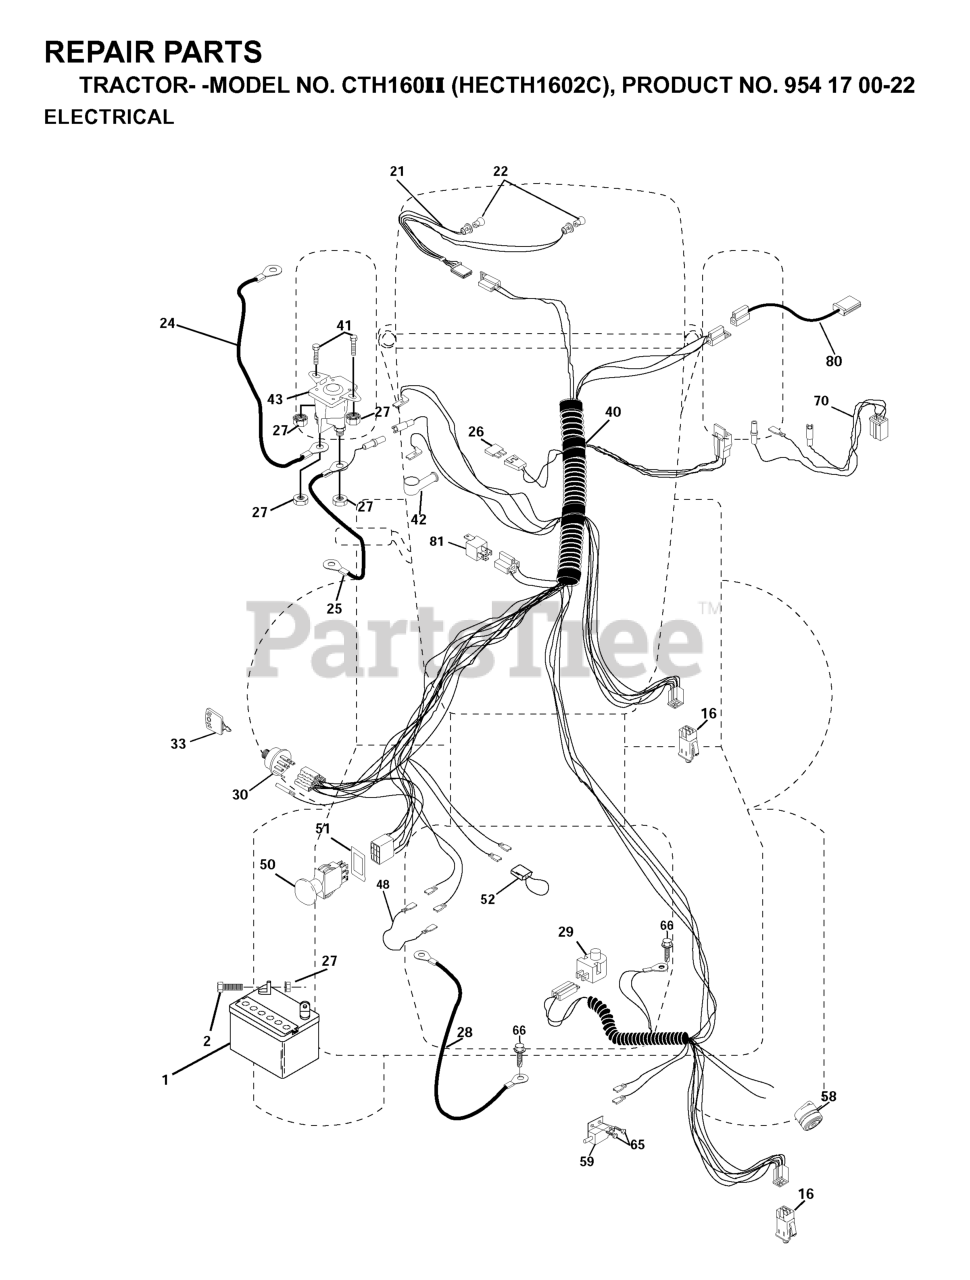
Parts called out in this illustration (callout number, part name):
1	BATTERY 12V .35 AMP
2	BOLT.HEX.1/4.X.3/4.DICHROMATE
16	SWITCH INTERLOCK
24	BATTERY CABLE GT
25	CABLE BATTERY
26	FUSE 20AMP
27	NUT
28	CABLE GROUND
29	PLUNGER SWITCH (COLOR:OLIVE)
30	IGNITION SWITCH
33	KEY MLD GEN DELTA
40	HARNESS.ING.CRD.ELECT
41	BOLT
42	TERMINAL COVER
43	REPL BY 532 1461-54
48	ADAPTER.AMMETER
50	RP.PTO.SWITCH.8 TERMINAL.BLACK
51	FRAME RETAINING RING
52	WIRE PROTECTION LOOP
58	BUZZER
65	Screw, Hex Wsh. Tap #10-16 x 1/2
80	HARNESS, CLUTCH
81	RELAY.ASSY.T
